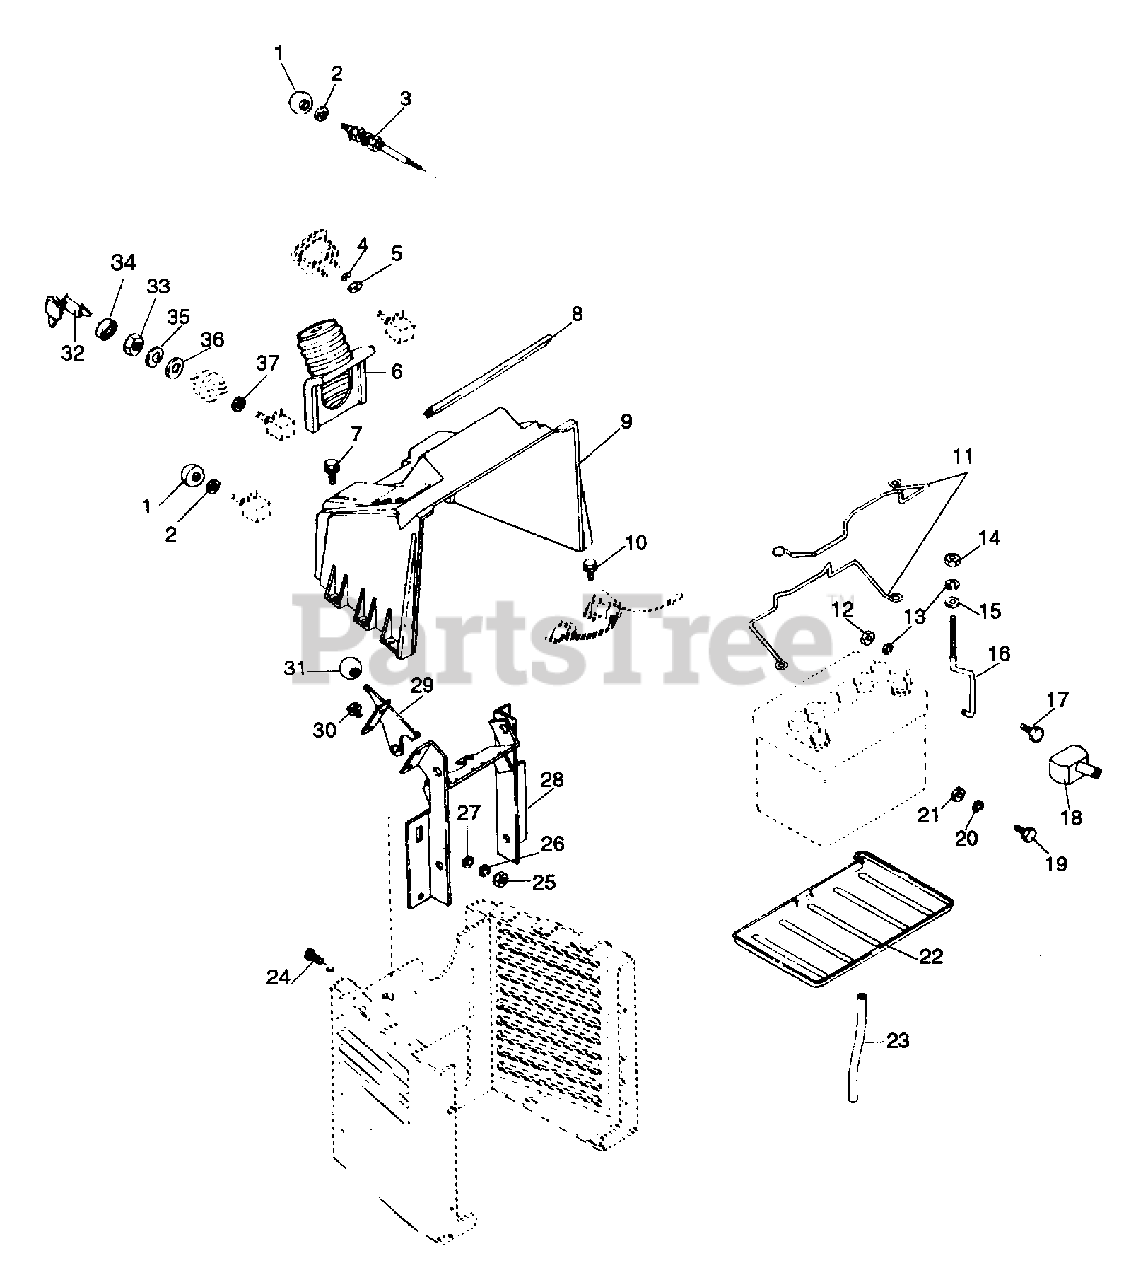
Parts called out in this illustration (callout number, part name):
1	PUSH/PULL CONTROL KNOB
2	WSHR-FL-STL .382X.812X.023 PL
3	CHOKE CONTROL
4	WSHR-LK-EXT #10 ID X .022
5	NUT 10-32 PL
6	STEERING COLUMN BOOT
7	SCR-TAP 10-16X.50 HWH PL AB
9	DASH ASSEMBLY
10	SCR-TAP 10-24X.375 CRPH 1A
11	HOLD DOWN
12	NUT-HEX .250-20 PL
13	WSHR-LK .250X.077 HVY PL
14	NUT-LK-NYL .250-20 PL
15	WSHR-FL-STL .880X1.500X.0598
16	TIE DOWN
17	BLT-HEX .25-20X.63 PL GR2
18	INSULATOR
19	BLT-HEX .31-18X1.00 PL GR 2
20	WSHR-LK-EXT .313X.030 PL
21	NUT-FLG. .312-18 PL
22	BATTERY TRAY
23	DRAIN HOSE
24	BLT-RDHDSQNK .312-18X.62SHTPL
25	NUT-HEX .312-18
26	WSHR-LK .312X.097 PL HVY
27	WSHR-FL-STL.312X.734X.065PL
28	CONTROL SUPPORT
29	THROTTLE CONTROL
30	SCR-TAP 10-24X.375 HWH PL TR
31	THROTTLE CONTROL KNOB
32	KEY SET
33	NUT- PANEL .562-24 GRECO
33	CAP - IGNITION SWITCH
34	WSHR-LK-INT .563X.040 PL
35	WSHR-FL-STL .875X1.125X.048
36	WSHR-FL-STL .522X.735X.031 PL
